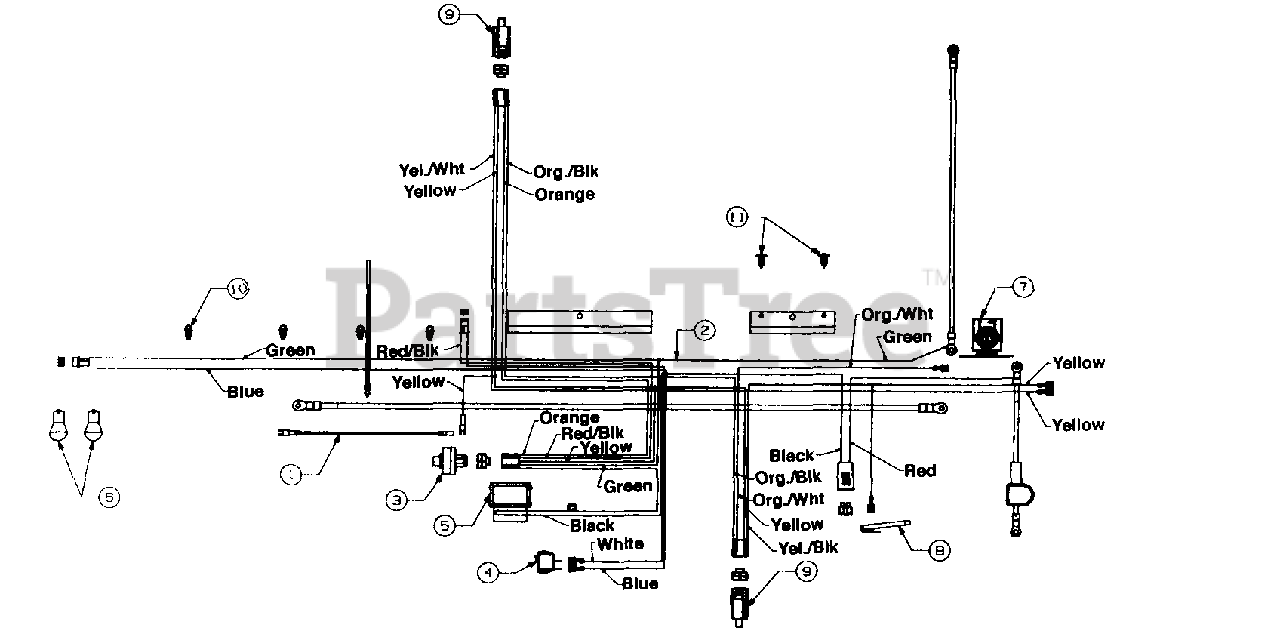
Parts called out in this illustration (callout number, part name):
1	Harness Adapter (Mag.)
2	Wire Harness w/Light Switch and Amp
3	Ignition Switch
4	Light Switch
5	Ammeter
6	Bulb (Headlight)
7	Solenoid
8	Safety Switch (Reverse)
9	Safety Switch
10	Wire Retainer Clip
11	Ratchet
